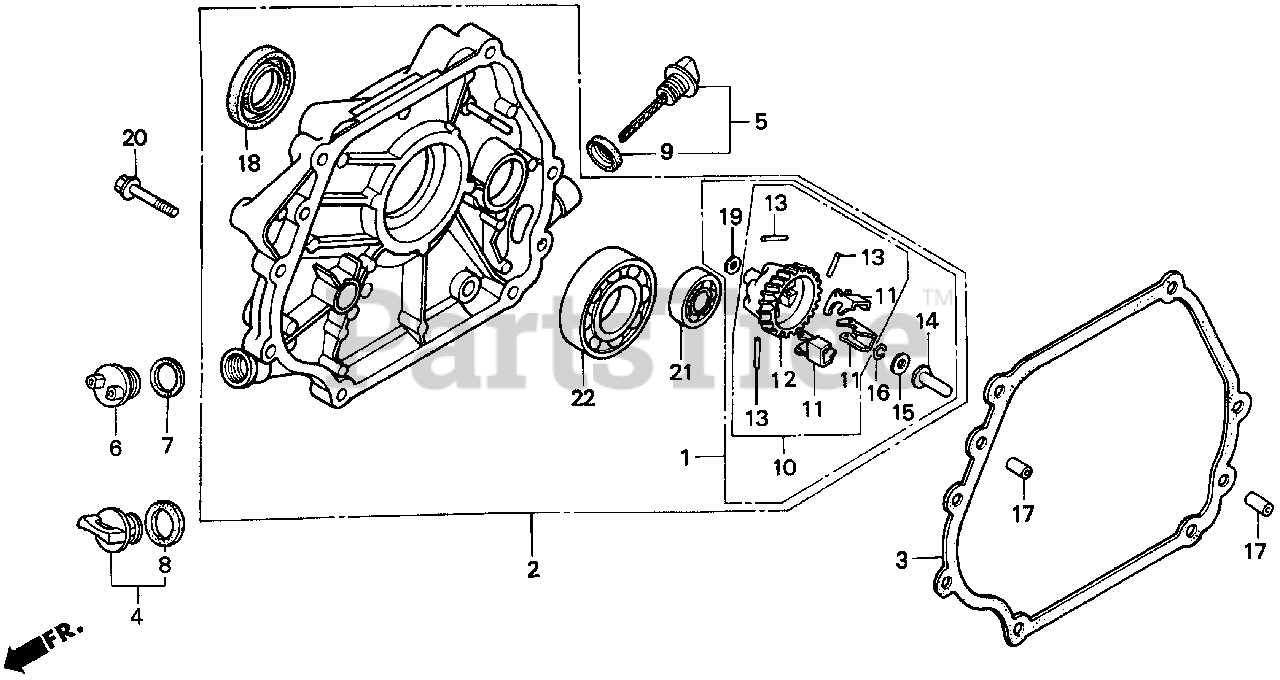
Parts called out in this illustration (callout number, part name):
1	GOVERNOR KIT
2	COVER ASSY., CRANKCASE (Q-TYPE)
3	GASKET, CASE COVER
4	CAP ASSY., OIL FILLER
5	CAP ASSY., OIL FILLER
6	CAP, OIL FILLER
7	GASKET, OIL FILLER CAP
8	GASKET, OIL FILLER CAP
9	GASKET, OIL FILLER CAP
10	GOVERNOR ASSY.
11	WEIGHT, GOVERNOR
12	HOLDER, GOVERNOR WEIGHT
13	PIN, GOVERNOR WEIGHT
14	SLIDER, GOVERNOR
15	WASHER (6X16)
16	CLIP, GOVERNOR HOLDER
17	PIN, DOWEL (8X12)
18	OIL SEAL (35X52X8)
19	WASHER, PLAIN (6MM)
20	BOLT, FLANGE (8X40)
21	BEARING, RADIAL BALL (6202)
22	BEARING, RADIAL BALL (6207)
